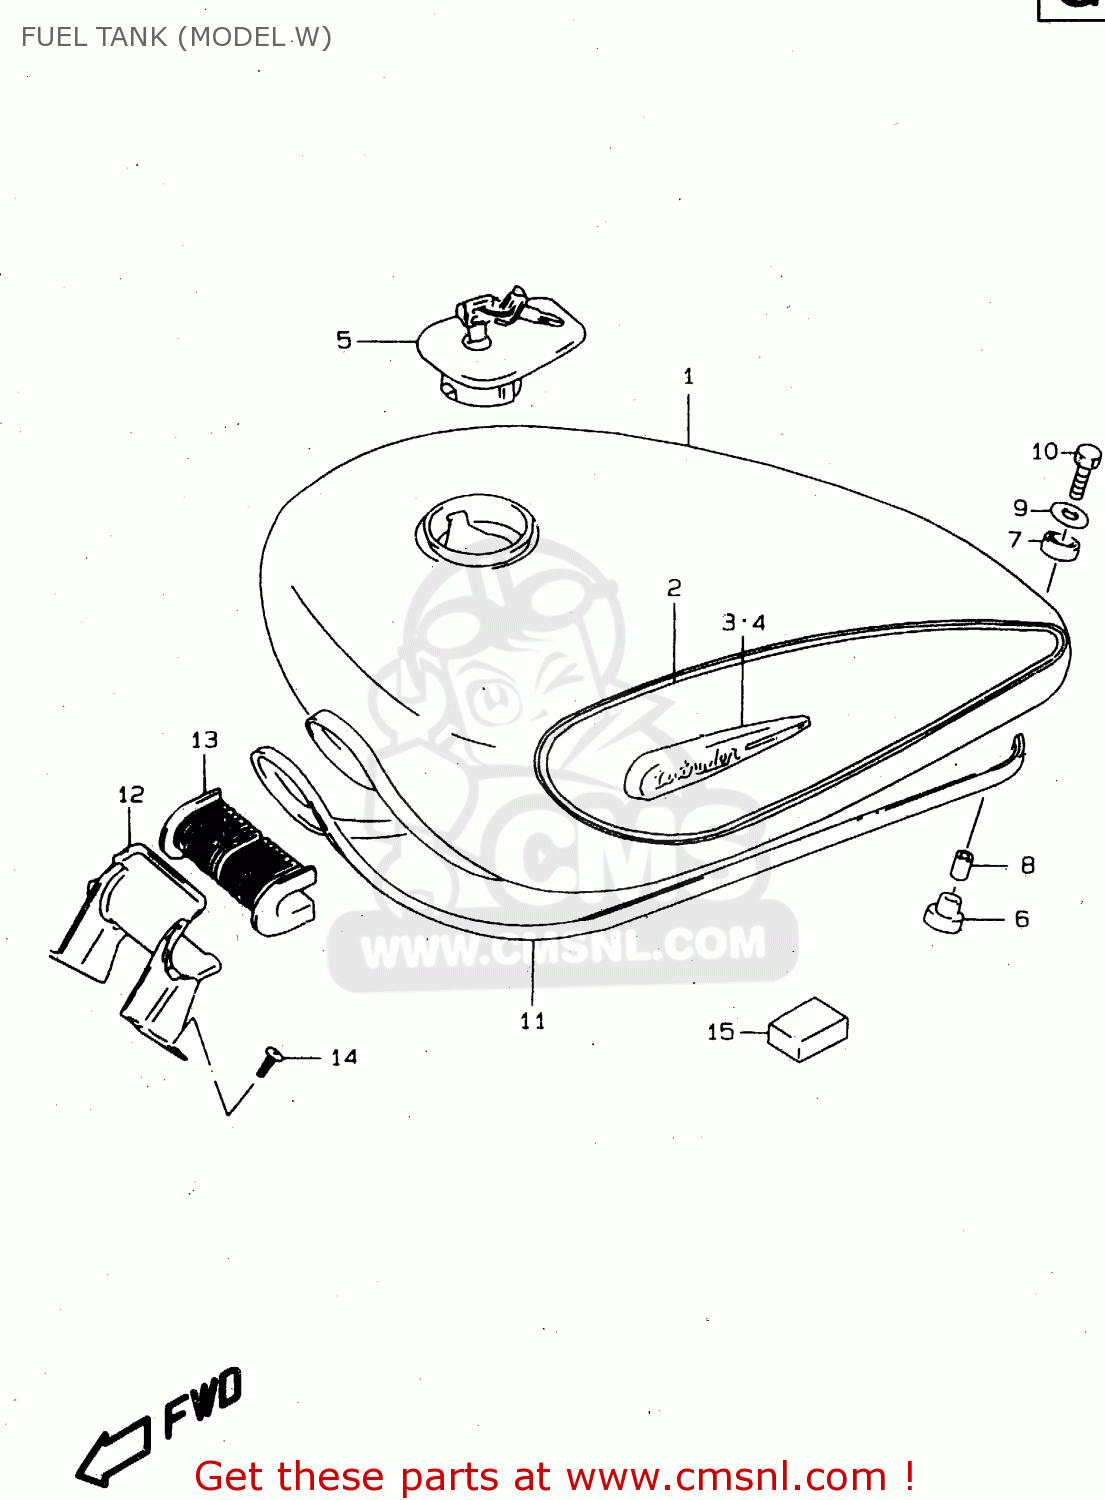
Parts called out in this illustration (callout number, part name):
1	TANK ASSY,FUEL
2	TAPE SET,FUEL TANK
3	EMBLEM,FUEL TANK,R
4	EMBLEM,FUEL TANK,L
5	CAP SET,FUEL TANK
6	CUSHION
7	CUSHION
8	SPACER(6.5X9X21.5)
9	WASHER (6.5X24X1.6)
10	SCREW
11	MOLDING
12	BRACKET,FUEL TANK FR
13	CUSHION,FUEL TANK FR
14	SCREW
15	CUSHION
